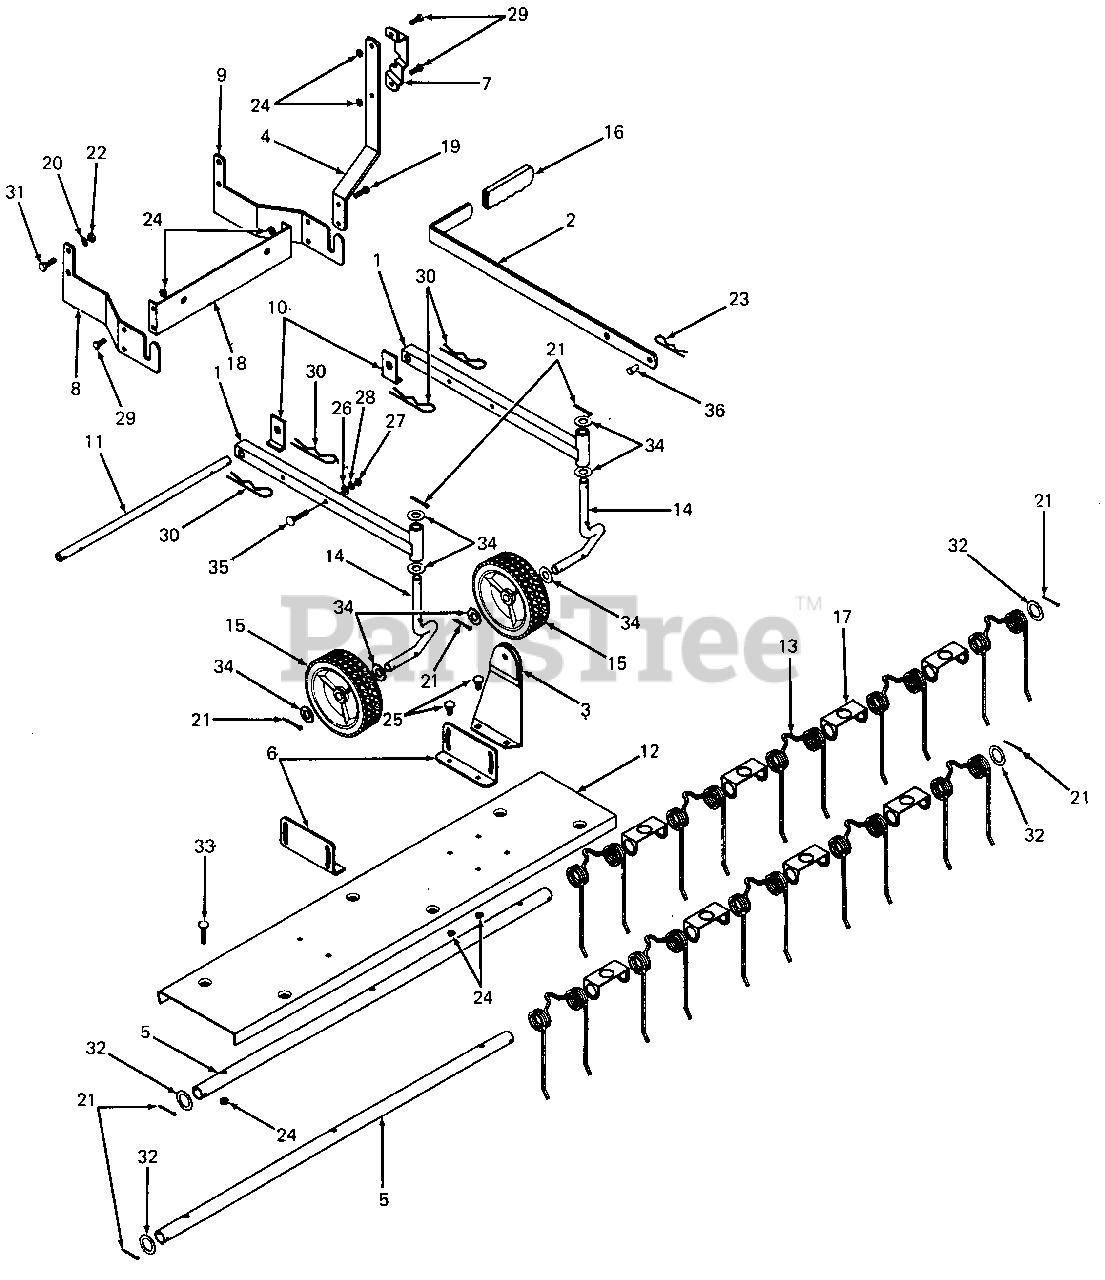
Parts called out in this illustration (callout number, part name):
1	Arm Assy, Mounting
2	Handle Assy, Lift
3	Bracket Assy, Lift Handle
4	Arm, Lift Handle
5	Tube, Spring Mounting
6	Bracket, Angle Mounting
7	Bracket, Handle Lock
8	Bracket, Hitch RH
9	Bracket, Hitch LH
10	Keeper, Plate
11	Shaft, Mounting
12	Shield, Spring Mounting
13	Spring, De-Thatcher
15	Wheel - Cream
16	Grip, Lift Handle
17	Bracket, Spring
18	Bracket, Weight Mount
19	Screw, Hex Cap, 5/16-18 X 1.0 Lg
20	Washer, Lock, 3/8
21	Pin, Cotter, 1/8 Dia X 1.25 Lg
22	Nut, Hex, 3/8-16 GR 5
23	Hairpin Cotter, 3/32
24	Nut, Hex Center Lock, 5/16-18
25	Bolt, Carriage, 5/16-18 X .75 Lg
26	Washer, Flat, .344 X .62 X .063
27	Nut, Hex, 5/16-18
28	Washer, Lock, 5/16
29	Screw, Hex Cap, 5/16-18 X .75 Lg GR 5
30	Hairpin Cotter, 1/8
31	Screw, Hex Cap, 3/8-16 X 1.0 Lg GR 5
32	Washer, Flat, 1.06 ID X 1.6 OD X 16 Ga
33	Bolt, Carriage, 5/16-18 X 1.5 Lg
34	Washer, Pivot, 21/32
35	Bolt, Carriage, 5/16-18 X 1.75 Lg
36	Pin, Clevis, 3/8 Dia X .75 Lg
